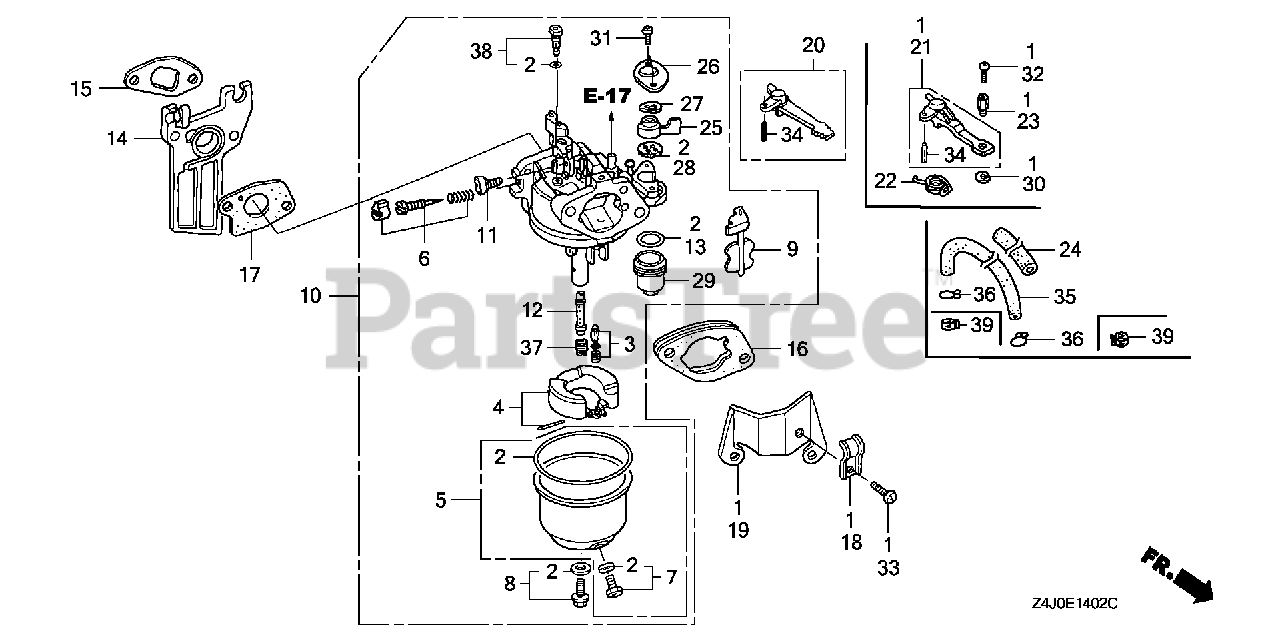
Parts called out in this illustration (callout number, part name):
2	GASKET SET
3	VALVE SET, FLOAT (SEAT NOT INCLUDED)
5	CHAMBER SET, FLOAT
6	SCREW SET, PILOT
7	SCREW SET, DRAIN
8	SCREW SET
10	CARBURETOR ASSY. (BE65B B/C)
11	SCREW, THROTTLE STOP
12	NOZZLE, MAIN
13	GASKET, FUEL STRAINER CUP
14	INSULATOR, CARBURETOR
15	GASKET, INSULATOR
16	SPACER, CARBURETOR
17	GASKET, CARBURETOR
20	LEVER, CHOKE (STD)
24	RUBBER, SUPPORTER
25	LEVER, PETCOCK
26	PLATE, LEVER SETTING
27	SPRING, PETCOCK LEVER
28	GASKET, PETCOCK
29	CUP, FUEL STRAINER
31	SCREW, PAN (3X6)
34	PIN, SPRING (2X12)
35	TUBE, FUEL (4.5X300) (FKM)
35	BULK HOSE, FUEL (4.5X3000) (4.5X300)
36	CLIP, TUBE (B8)
37	JET, MAIN (#65)
37	JET, MAIN (#68)
37	JET, MAIN (#70)
38	JET SET, PILOT (#35)
39	CLAMP, TUBE (D8)
